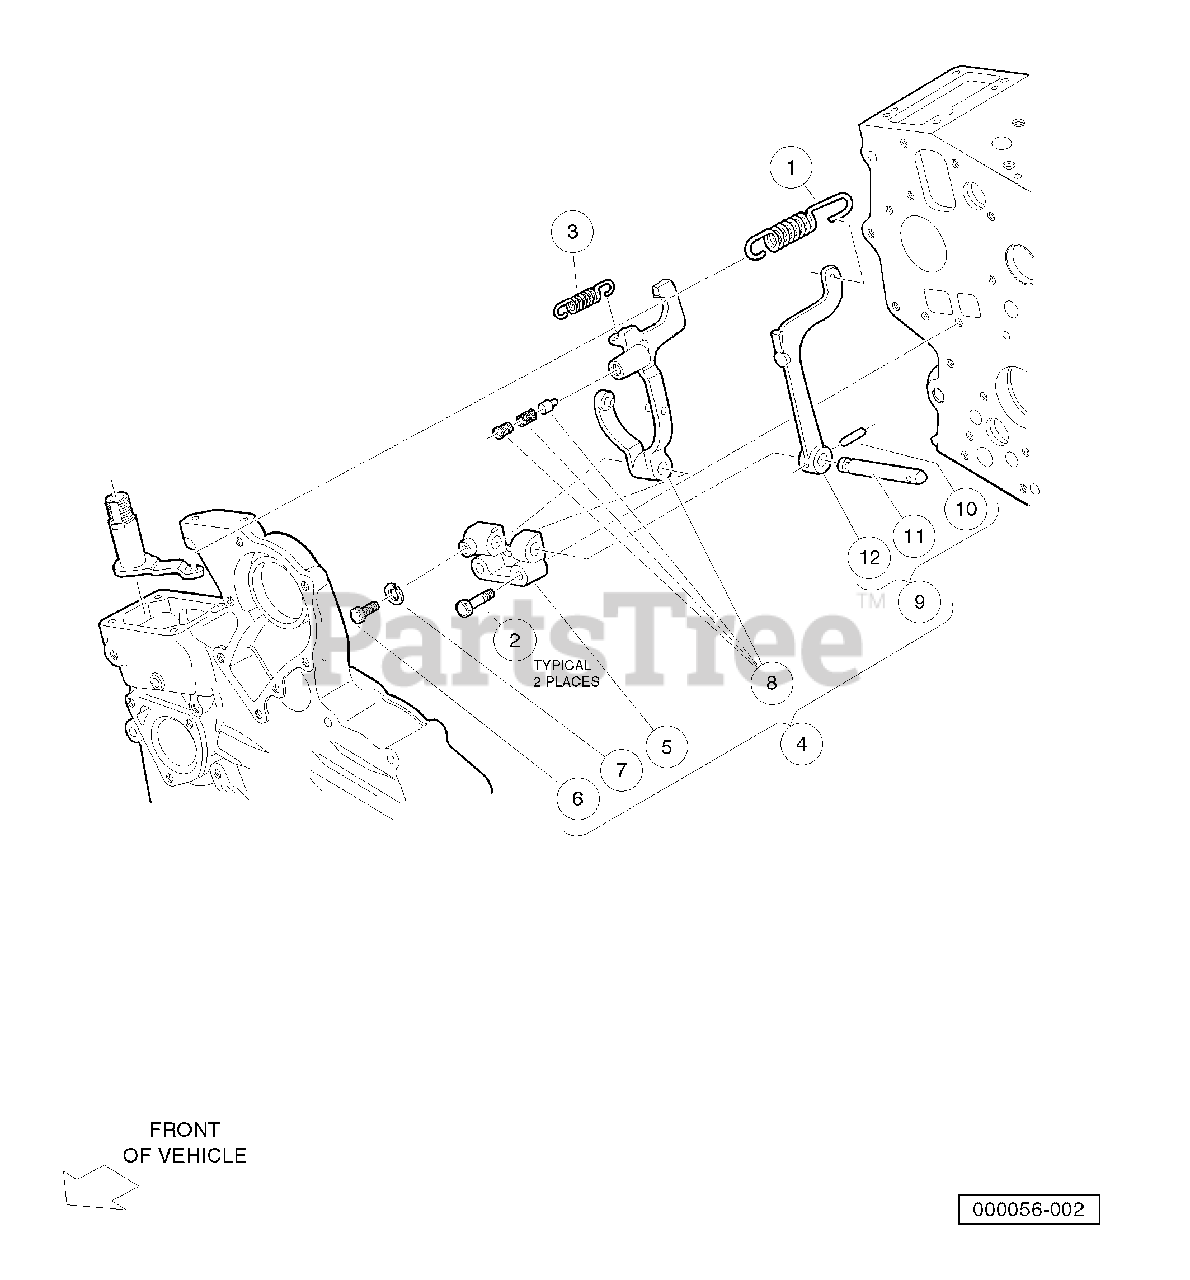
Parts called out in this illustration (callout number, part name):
1	Spring, Governor
2	Bolt, M5 X 0.75 X 25
3	Spring, Start
4	Assembly, Governor Fork
5	Holder, Fork Lever
6	Bolt, M5 X 0.75 X 11
7	Washer, Spring, M5
8	Lever, Fork, Middle, D722 CB
9	Assembly, Governor Fork Level, Lower, D722 CB
10	Pin, Spring
11	Shaft, Fork Lever
12	Lever, Fork, End, D722 CB
